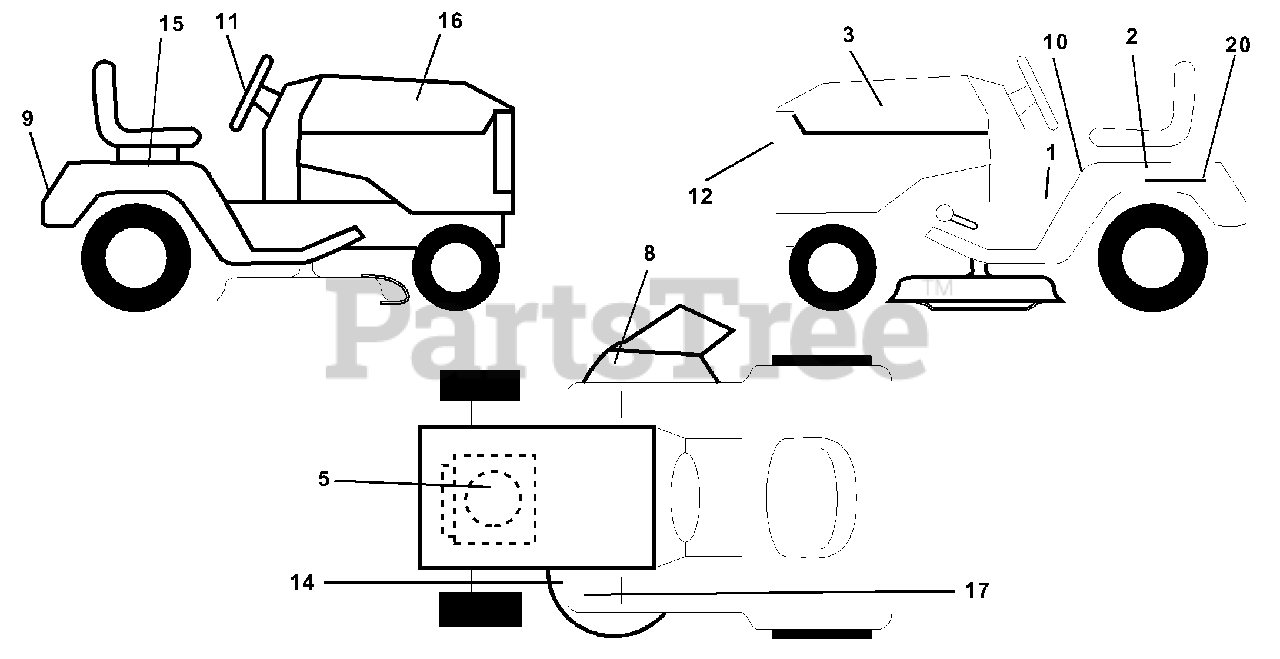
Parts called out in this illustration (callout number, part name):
1	Decal Oper
2	Decal Fender Side Lh
3	Decal Hood LH
5	Decal HP Engine
8	Decal Warning Mult-Language
9	Decal Fender Logo
10	Decal Fender Danger E/F
11	Decal Ins Strg Whl
12	Decal Grille
14	Decal V-Belt Schematic
15	Decal Fender Side Rh
16	Decal Hood Rh
17	Decal Clutch/Brake
20	Decal Bat Dan/Psn
